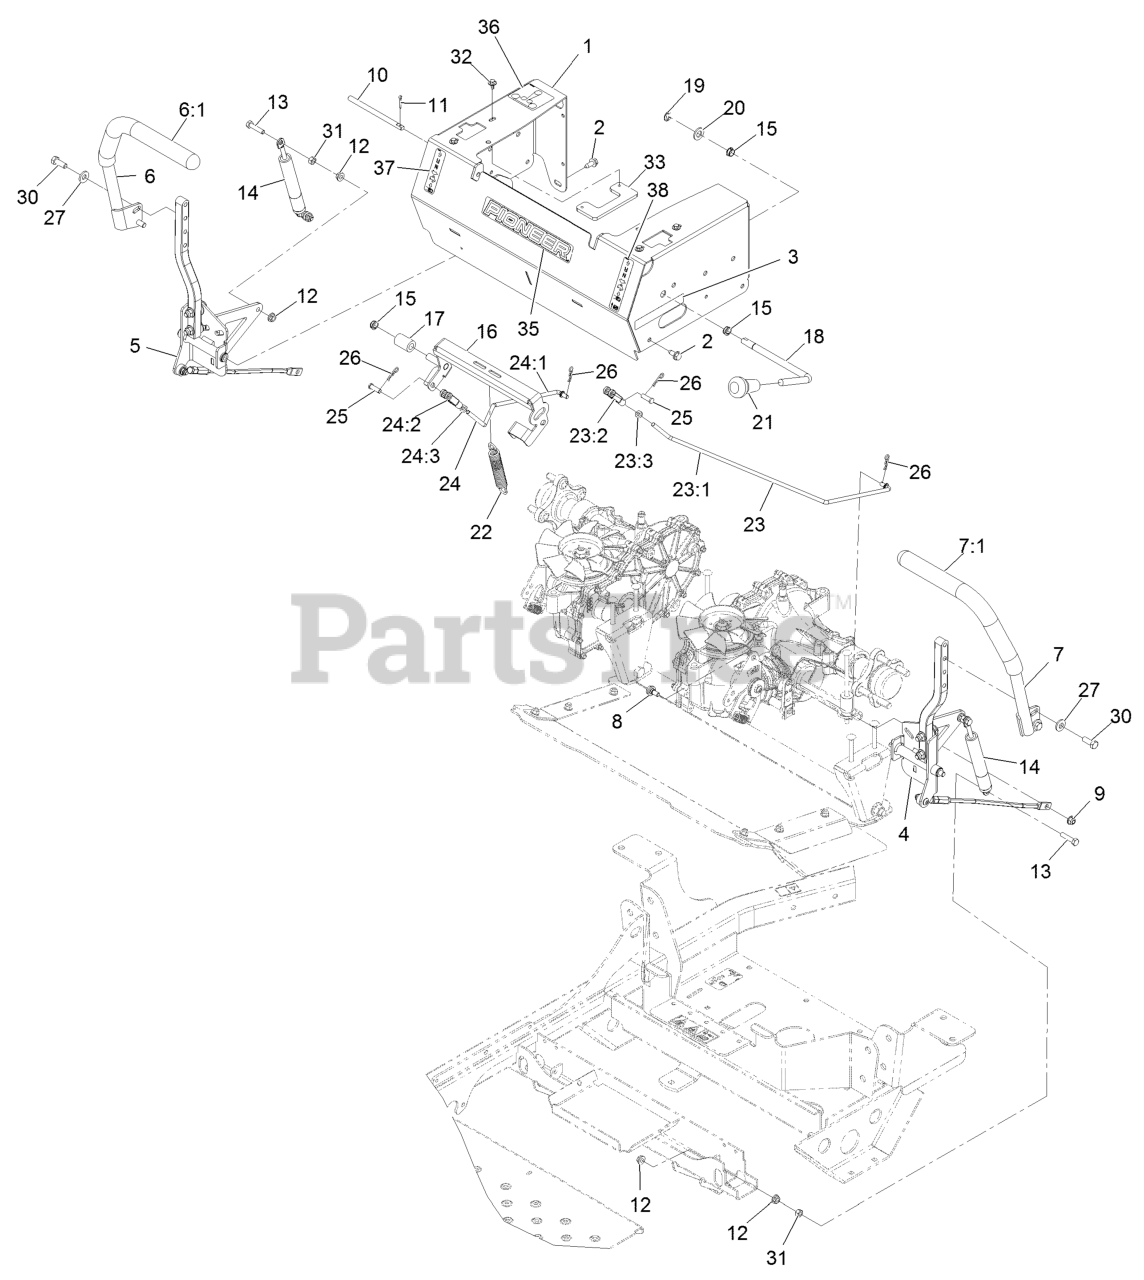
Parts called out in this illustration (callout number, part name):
1	ASM-MOT CTRL FRM W/DCL
2	Screw-HWH 5/16-18 X 3/4 Tf
3	Decal-S-Series
4	Motion Control ASM-LH
5	Motion Control ASM-RH
6	RH HANDLE ASM
7	LH HANDLE ASM
8	BOLT-SHOULDER,HFH
9	NUT-HF, NI
10	PIN-CONTROL PIVOT
11	PIN-COTTER
13	SCREW-HH
14	DAMPER-MOTION CONTROL
15	BUSHING,SNAP
16	ASM-BRAKE CENTER ARM
18	HANDLE,BRAKE
19	RING-RETAINING, EXTERNAL
20	WASHER-FLAT
22	SPRING-DECK, ENGAGEMENT
23	BRAKE LINKAGE ASM-LH
23:1	LINKAGE,BRAKE LH
23:2	YOKE-ADJUSTABLE
23:3	NUT-JAM
24	BRAKE LINKAGE ASM-RH
24:1	LINKAGE-BRAKE, RH
24:2	YOKE-ADJUSTABLE
24:3	NUT-JAM
25	PIN-CLEVIS
26	PIN-COTTER
27	WASHER-BELLEVILLE
30	SCREW-HH
31	NUT-HEX
32	SCREW-HHFTF
33	STOP-MOTION CONTROL
35	Decal-Pioneer Logo
36	DECAL-ROUTING, BELT
37	DECAL-CONTROL, MOTION
38	DECAL-MOTION CONTROL,PARK
